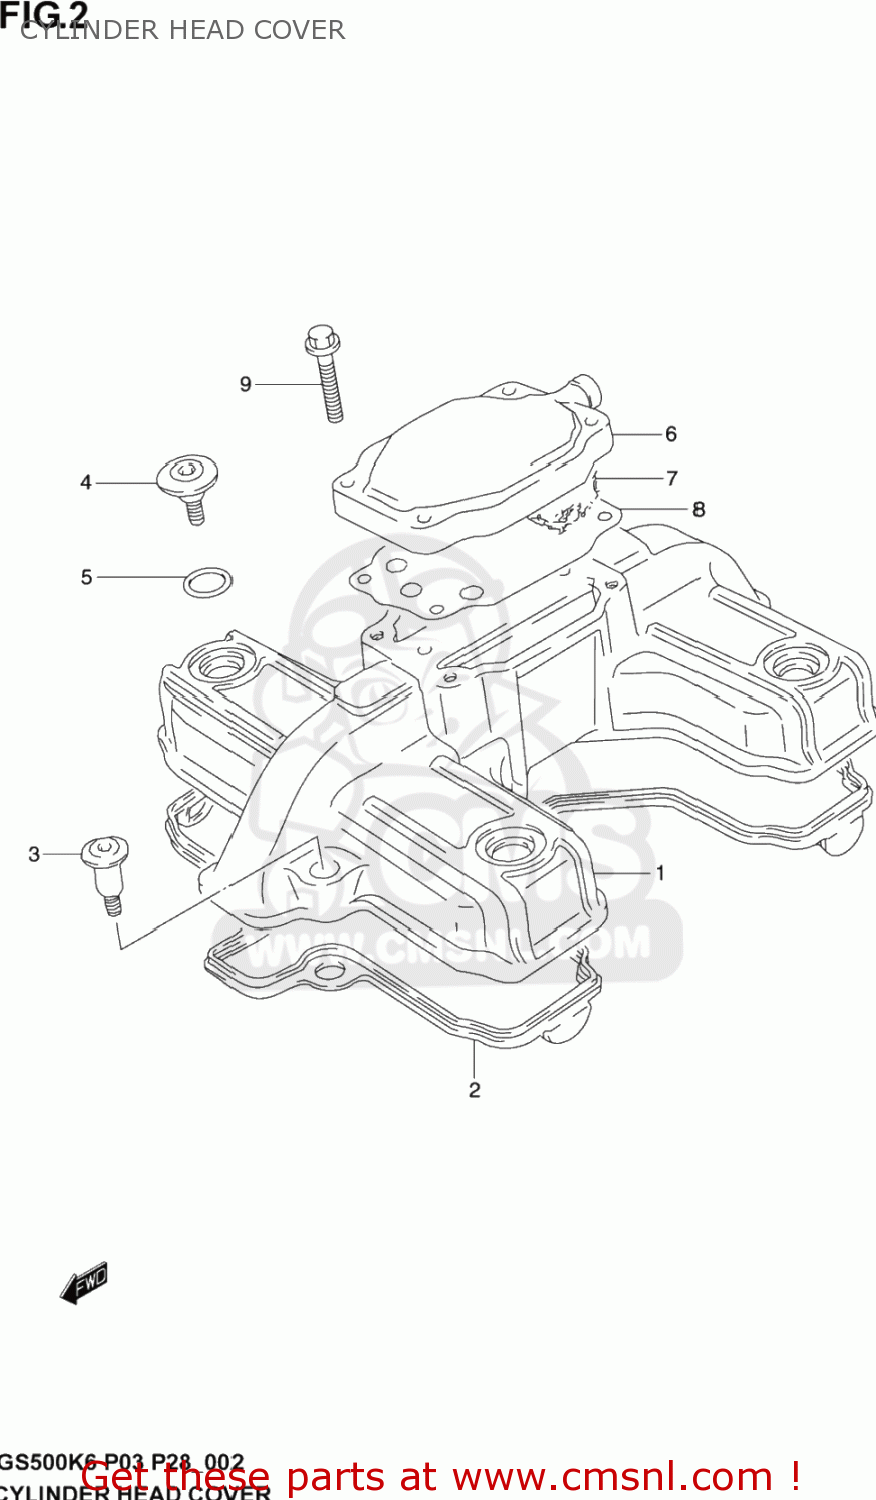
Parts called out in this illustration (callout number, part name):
1	COVER,CYLINDER HEAD
2	GASKET,CYLINDER HEAD COVER (NAS)
3	BOLT(7X31)
4	BOLT(7X17.5)
5	O RING(D:1.9,ID:14.5)
6	COVER,BREATHER
7	SEPARATOR,OIL BREATHER COVER
8	GASKET,BREATHER COVER (NAS)
9	BOLT
